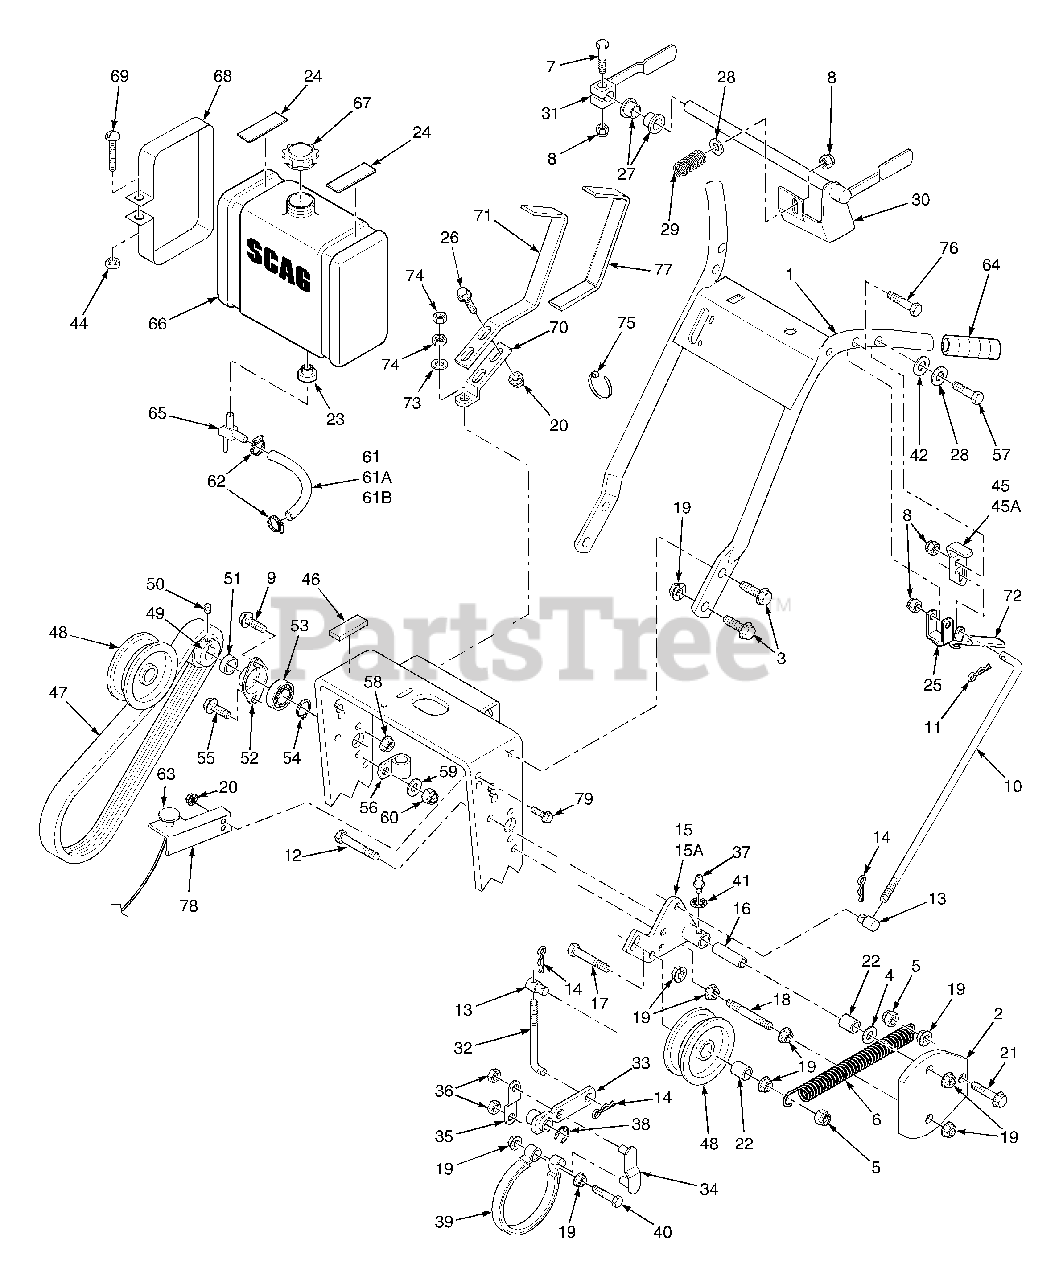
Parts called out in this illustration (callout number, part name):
1	Handle Assembly
2	Belt Guard
3	Capscrw, 3/8-16 x 1" Serr. Flg.
4	Washer, 3/8" (.391 x .938 x .105)
5	Nut, 3/8-16 Elastic Stop
6	Spring, Idler
7	Bolt, 5/16-18 x 1-1/4" Hex Head
8	Nut, 5/16-18 Elastic Stop
9	Capscrew, 1/4-20 x 3/4" Hex Head
10	Control Rod, Steering
11	Hair Pin, Small
12	Bolt, 3/8-16 x 4-1/2" Hex Head
13	Swivel Joint
14	Hair Pin, Large .094 Diameter
15	Idler Bracket, RH
15A	Idler Bracket, LH
16	Idler Sleeve
17	Bolt, 3/8-16 x 3/4" Hex Head
18	Support Belt Guard
19	Nut, 3/8-16 Serrated Flange
20	Nut, 5/16-18 Serrated Flange
21	Cpscrw, 3/16-18 x 1-1/4" Serr. Flg.
22	Spacer
23	Bushing
24	Rubber Pad, (Upper)
25	Steering Lever
26	Capscrew, 5/16-18 x 1" Serr. Flg.
27	Bushing
28	Washer, 5/16 (.375 x .875 x .083)
29	Spring, Operator Presence
30	Operator Presence Lever, LH
31	Operator Presence Lever, RH
32	Brake Rod
33	Brake Lever
34	Brake Link
35	Brake Link Plate
36	Nut, 3/8 Push-on
37	Grease Fitting, Straight 1/4-28
38	Retaining Ring, 5/8 Ext. "E"
39	Brake Band
40	Bolt, 3/8-16 x 2" Hex Head
41	1/4" Internal Tooth Lockwasher
42	Curved Spring Washer
43	Socket Head Capscrew #8-32 x 1/2"
44	Nut, 1/4-20 Hex
45	Neutral Latch, RH
45A	Neutral Latch, LH
46	Rubber Pad (Lower)
47	Belt, Wheel Drive
48	Idler Pulley, Wheel Drive
49	Pulley, Jackshaft
50	Setscrew, Hex Socket Knurl Cup Pt. 5/16-18 (nylock)
51	Spacer, Jackshaft Pulley
52	Flange, Jackshaft Bearing
53	Bearing, Jackshaft
54	Retaining Ring, 5/8 Ext. Basic
55	Capscrew, 1/4-20 x 1" Serr. Flg.
57	Bolt, 5/16-18 x 2" Hex Head
58	Nut, 1/4-20 Serrated Flange
59	Flatwasher, 5/16 (.375 x .875 x .083)
60	Nut, 1/4-20 Elastic Stop
61	Fuel Hose,1/4" ID, 10" (KH Only)
61A	Fuel Hose,1/4" ID, 23" (KA Only)
61B	Fuel Hose,1/4" ID, 26" (Honda Only)
62	Clamp, Fuel Hose
63	Choke Control
64	Grip, Handle
65	Valve, Fuel Shut Off
66	Fuel Tank Assy.
67	Fuel Tank Cap
68	Strap, Fuel Tank
69	Screw, 1/4-20 x 2" Rnd Hd Slotted
70	Shift Lever
71	Shift Lever Extention
72	Grip, Steering Lever
73	Washer, 3/8 (.391x .938 x .105)
74	Nut, 3/8-24 UNF
75	Cable Tie
76	Bolt, 5/16-18 x 2-1/2"
77	Grip, Shift Handle
78	Bracket, Choke Mt.
79	Capscrew, 5/16-18 x 3/4" Serr. Flg
